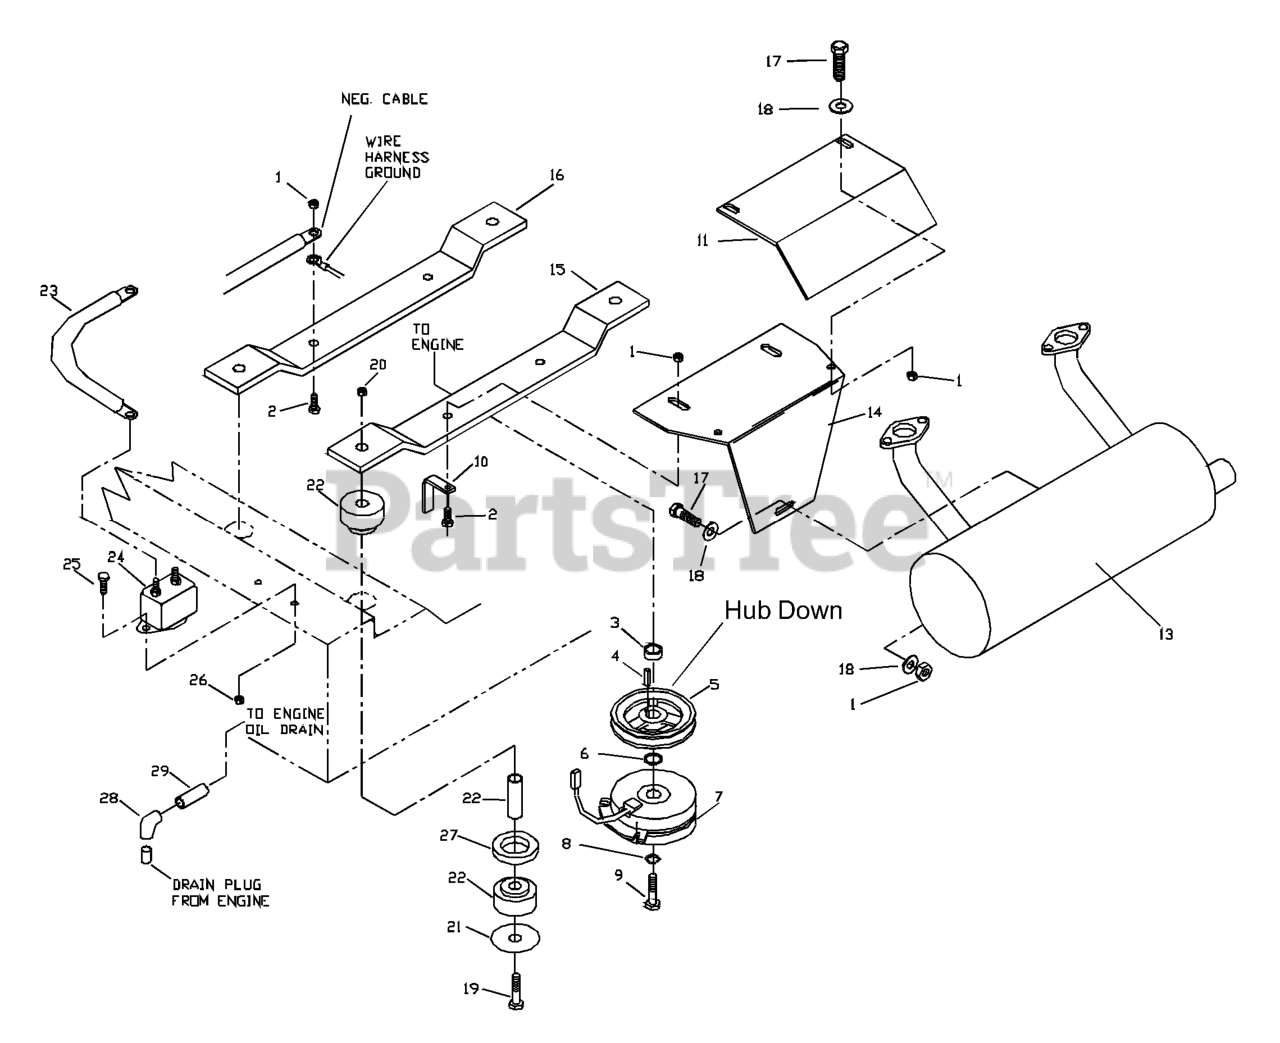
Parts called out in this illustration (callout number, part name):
1	NUT 5/16C CENTERLOCK
2	HCS 5/16C X 1 3/4
3	SPACER .70"
4	KEY 1/4 SQ X 1.0
6	SPACER .508"
8	7/16 LOCKWASHER
9	BOLT 7/16F X 2 1/2
10	CLUTCH TIE DOWN
11	MUFFLER GUARD, PAINT
12	KOH PIGTAIL
12	KAW PIGTAIL
13	MUFFLER KOH
13	MUFFLER KAW.
14	MUFFLER MT, PAINT
15	ENGINE MOUNT
16	ENGINE MOUNT
17	HCS 5/16C X 3/4
18	WASHER 5/16 FLAT
19	HCS 1/2C X 3 1/4
20	NUT 1/2-13 HEX NYLOC ZD
21	ISOLATOR WASHER
23	CABLE POSITIVE
25	HCS 1/4C X 5/8
26	NUT 1/4C CENTER LOCK
27	ISOLATOR SPACER
28	90 DEG.ELBOW 3/8NPT
29	PIPE 3/8 NPT 1-1/2
32	HCS 5/16-18X2
